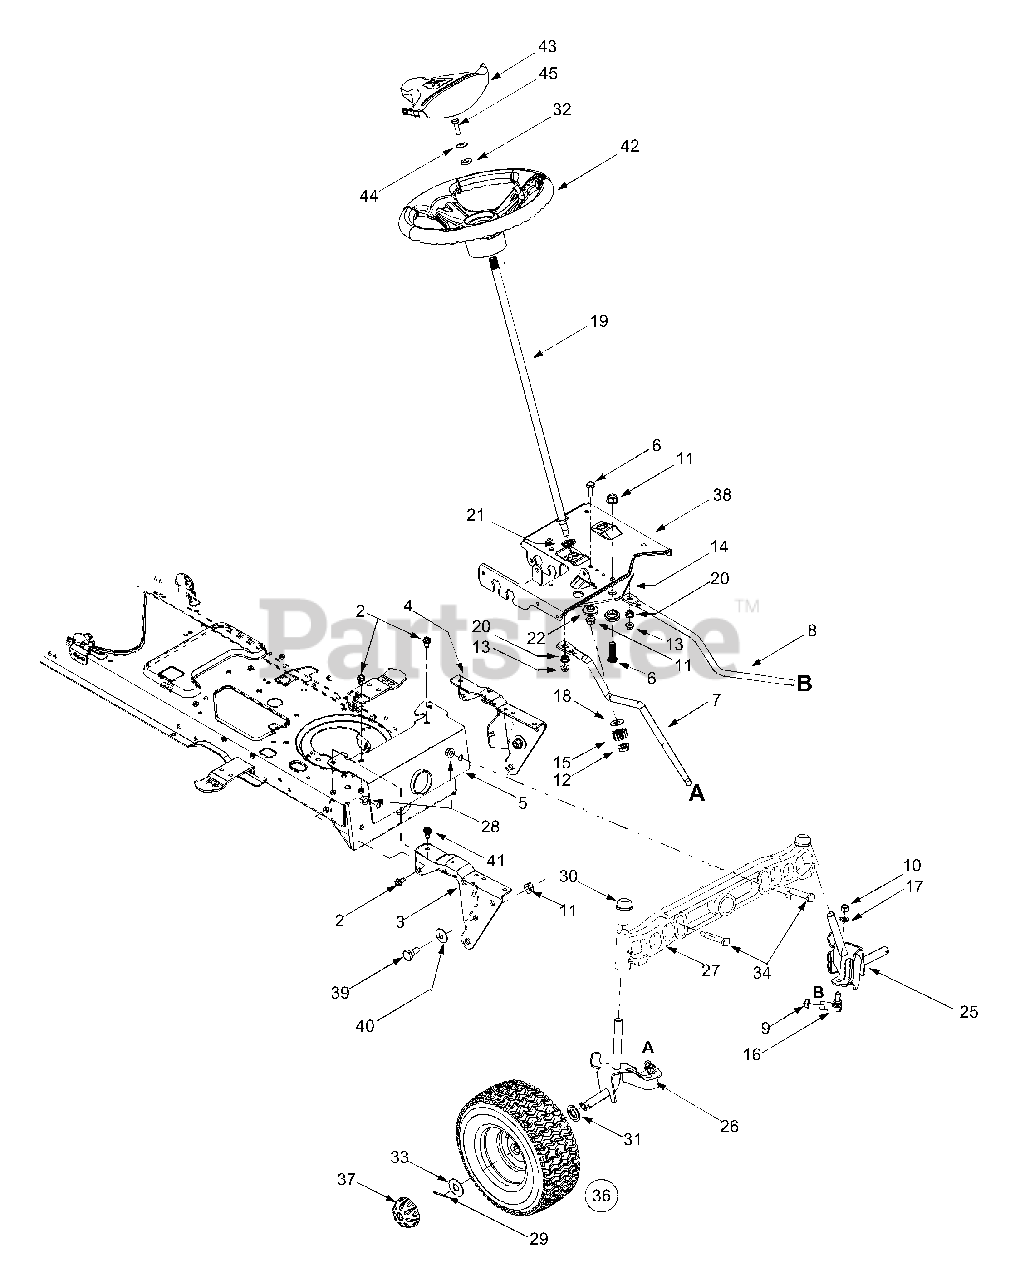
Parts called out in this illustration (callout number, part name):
1	Pivot Bar: Axle
2	Self-tapping Screw, 16-18 x .625
6	Hex Cap Screw, 3/8-16 x 1.25 (Grade 5)
7	RH Drag Link
9	Jam Nut, 7/16-20
10	Hex Nut, 3/8-24
11	Lock Nut, 3/8-16
12	Flange Lock Nut, 7/16-20
13	Lock Nut, 5/16-18
14	Steering Gear, 11/90 Ratio
15	Steering Pinion Gear
16	Ball Joint, 7/16-20
18	Flat Washer, .51 x 1.12 x .06
19	Steering Shaft, .625 OD x 24.4
20	Plastic Bushing, .38 ID
21	Hex Flange Bearing, 5/8
22	Shoulder Spacer, .38 ID
23	Standard Steering Wheel, 13.25
24	Steering Wheel Cap, Round
25	LH Axle Assembly, .750 Diameter
26	RH Axle Assembly, .750 Diameter
28	Lock Nut, 3/8-16
30	Push Cap, .625
31	Flat Washer, .64 x 1.0 x .12
32	Flat Washer, .406 x .875 x .105
33	Flat Washer, .635 x 1.589 x .06
34	Shoulder Screw, .5 x 2.2, 3/8-16
37	Deluxe Hub Cap
39	Shoulder Screw, 3/8-16
40	Bell Washer, .39 x 1.13 x .062
41	Self-tapping Screw, 5/16-18 x .75
42	Steering Wheel, Soft Grip, Three Spoke
43	Steering Wheel Cap, Round
45	Hex Bolt, 5/16-18 X 1
